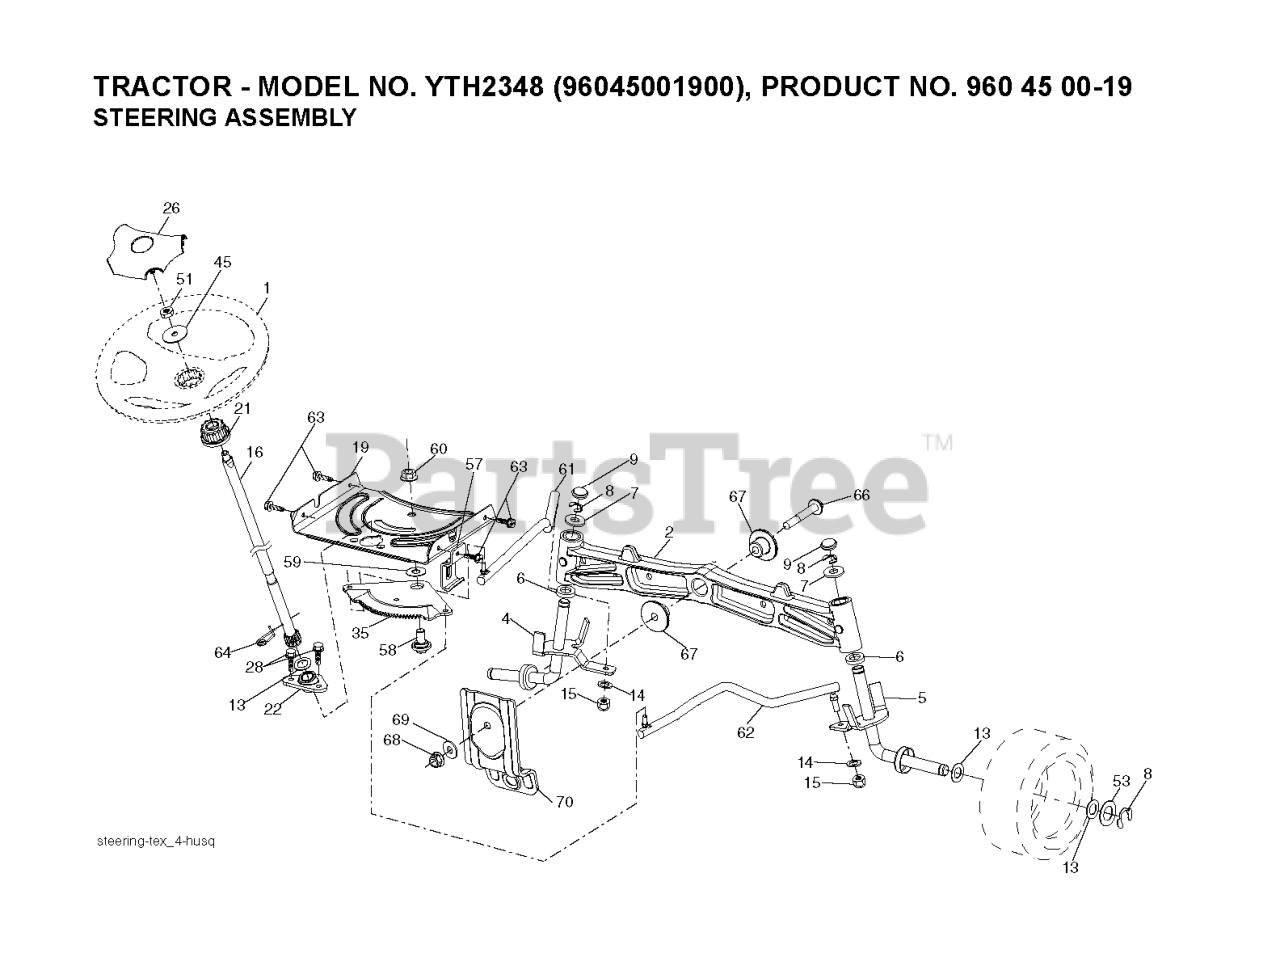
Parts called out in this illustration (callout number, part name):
1	WHEEL STEERING
2	AXLE.CAST.IRON
4	SPINDLE.WELDED.LH.15"TEX
5	SPINDLE.WELDED.RH.15"T
6	THRUST WASHER
9	CAP.SPINDLE.BLACK
14	WASHER, LOCK 3/8
15	NUT CROWNLOCK 3/8-24
16	SHAFT, STEERING
19	PLATE.STEER.DDL.NLT/NG
21	ADAPTER, WHEEL STNG..
22	BUSHING.ASM.STEERING.A
26	RP INSERT.CAP.WHL.STRG.HUSQ.
28	SCREW, 3/8-16X3/4
35	GEAR.SECTOR.PLATE.DDL.
45	WASHER 9/16"ID, 2 3/8"OD
51	NUT.HEX.1/2-20
53	WASHER.HARDENED
57	BRKT.UPSTOP.GT/LT.TEX
58	BOLT.SHOULDER.SECTOR.P
59	WASHER.THURST.SECTOR.S
60	NUT FLANGE LOCK 5/8-11
61	DRAGLINK.LH.BALLSTUD.D
62	DRAGLINK.RH.BALLSTUD.D
63	SCREW
64	RETAINER.CLIP.SPRING.S
66	BOLT HEX FGHD 7/16-14 X 3 SERR
67	BUSHING.PM.FRONT AXLE
68	NUT.LOCK.FLANGE.7/16
69	WASHER.1.5X.505X.118
70	BRKT.DECK.SUSPENSION.F
